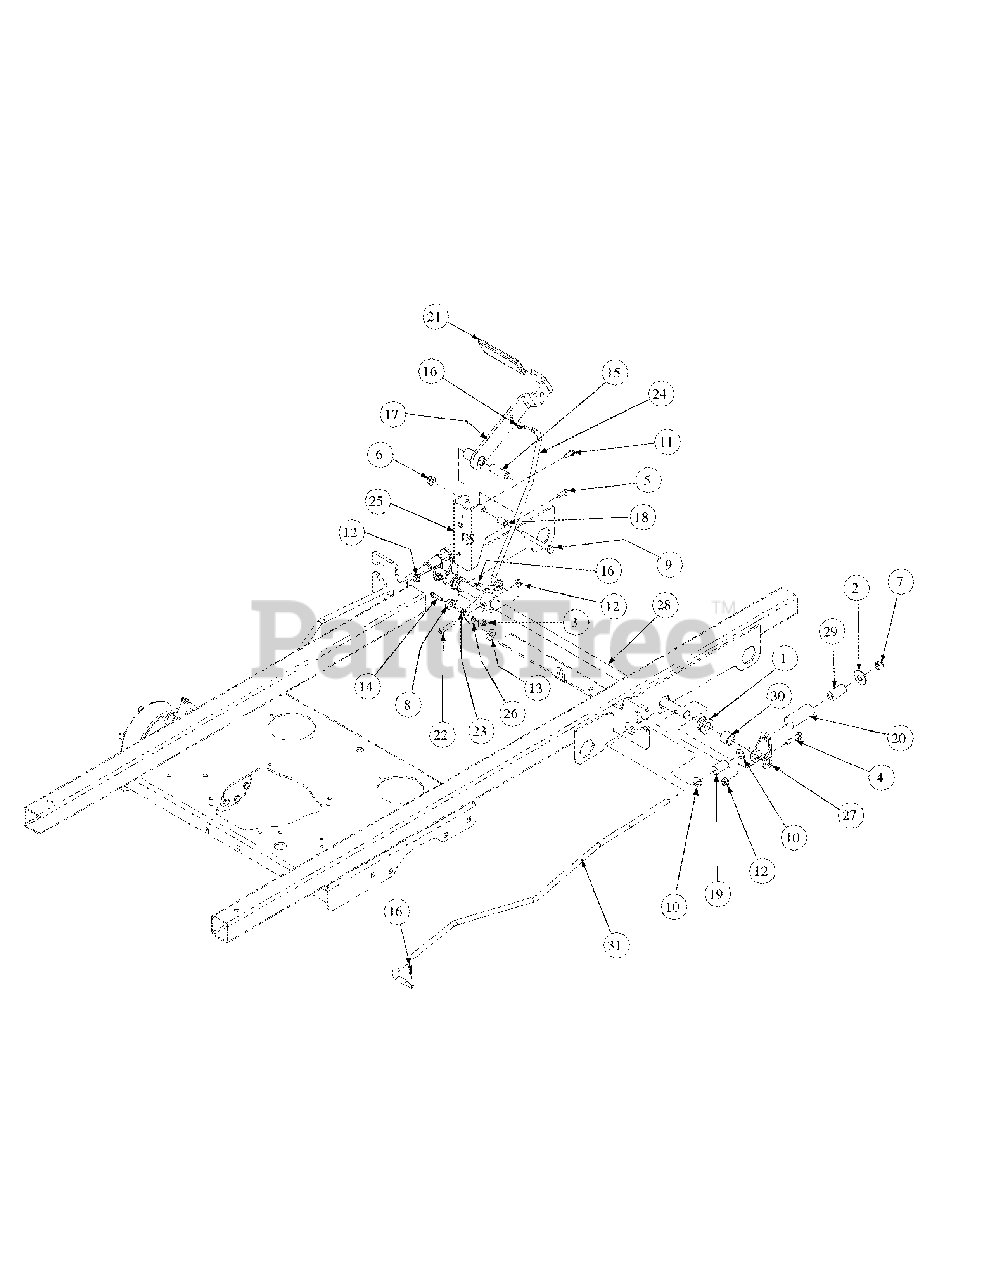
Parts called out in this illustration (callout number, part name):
1	Hex Flange Bearing, .752 ID
2	Washer, 1/2
3	Lock Nut, Nylon Insert, 1/4-20
4	Hex Cap Screw, 5/16-18 x 1-1/2
5	Hex Cap Screw, 5/16-18 x 1.0
6	Flange Lock Hex Nut, 3/8-16
7	Nut, 7/16-14, Nylock
8	Spacer, Control Rod
9	Hex Cap Screw, 3/8-16 x 3-1/4
10	Flat Washer, .469 ID, .875 OD, .105
11	Screw, TT, 1/4-20, 0.75, Hex Index Washer
12	Nut, Lock, Hex Flange, 5/16-18
13	Flat Washer, .406 ID x 1.0 OD x .105
14	Screw, TT, 1/4-20, 1.0, Hex Index Washer
15	Spacer, .39 x .63 x 1.75
16	Cotter Pin, .072 x 1.12 Lg
17	Brake Handle
18	Spacer, .375 x .50 x .75 Lg
19	Neutral Brake Spring
20	Force Brake Spring
21	Parking Brake Grip
22	Socket Head Capscrew, 5/16-18 x 1.50
23	Spacer, Pump Release
24	Brake Rod
25	Parking Brake Mounting Bracket
26	Brake Arm Assembly
27	Brake Arm Bracket
28	Pivot Brake Shaft
29	Hose, .5 ID x .78 OD, Low Pressure
30	Spacer, .76 ID x 1.0 OD x 3/4
31	Connector Rod Rod
